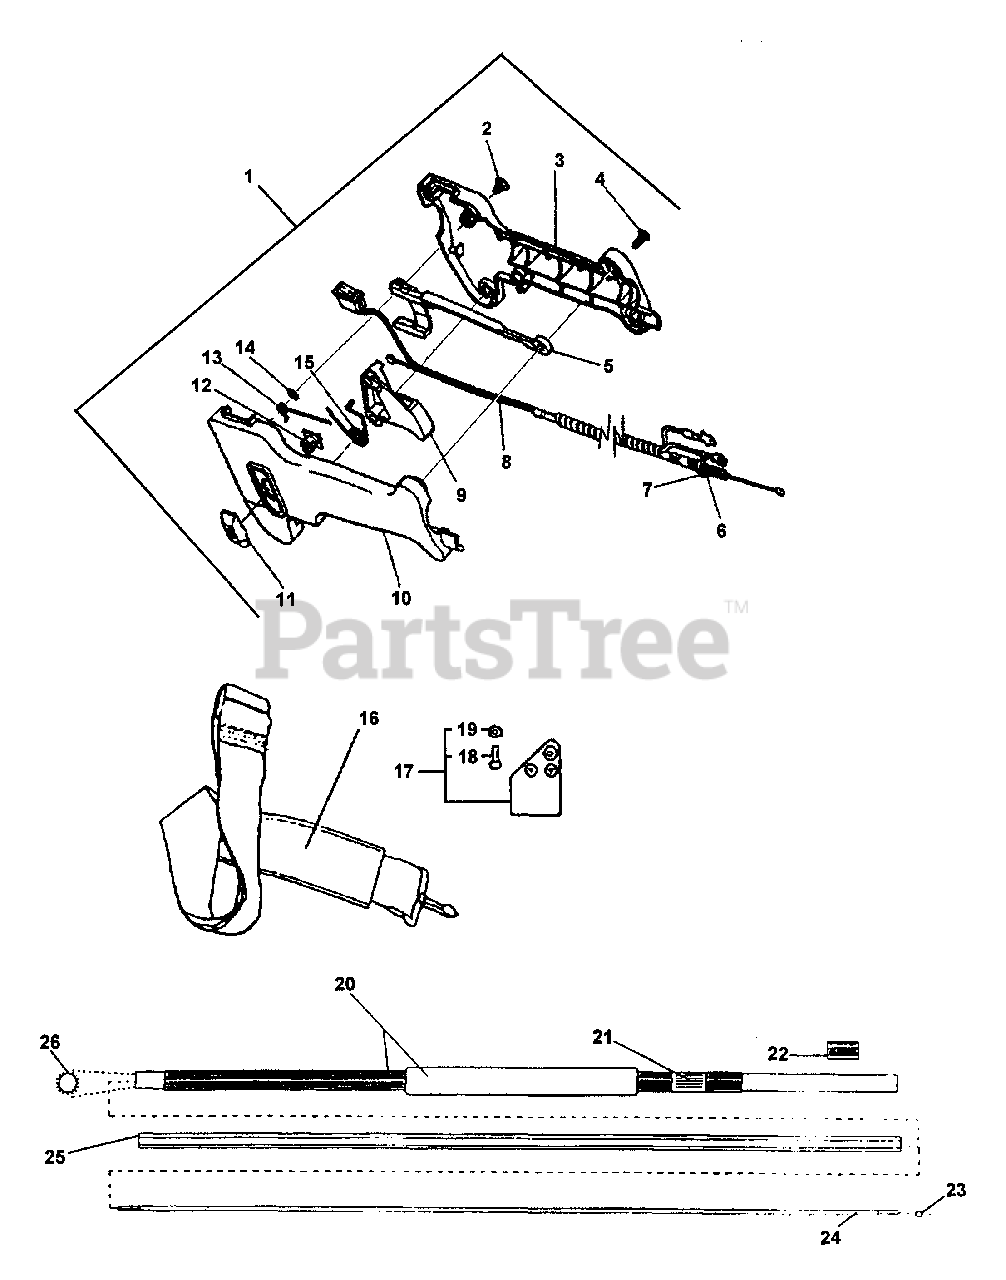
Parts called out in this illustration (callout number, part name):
1	CONTROL HANDLE ASSY
2	SCREW - 12×1/2"
3	HANDLE, RIGHT
4	SCREW
5	LEVER, TRIGGER LOCKOUT
6	WASHER - 6
7	NUT - 6
8	CONTROL CABLE ASSY
9	TRIGGER, THROTTLE
10	LEFT HANDLE
11	SWITCH, THROTTLE
12	LOCKOUT, TRIGGER
13	SPRING, THROTTLE ADVANCE
15	SPRING, TRIGGER
16	STRAP ASSY, SHOULDER
17	HANGER KIT
18	SCREW
19	NUT, LOCK 10-24 UNC
20	PIPE, MAIN
21	LABEL, CAUTION
22	SLEEVE, HOUSING 2-5/8"
23	LOCKWASHER - INTERNAL
24	DRIVESHAFT - FLEXIBLE
25	LINER - FLEXIBLE
